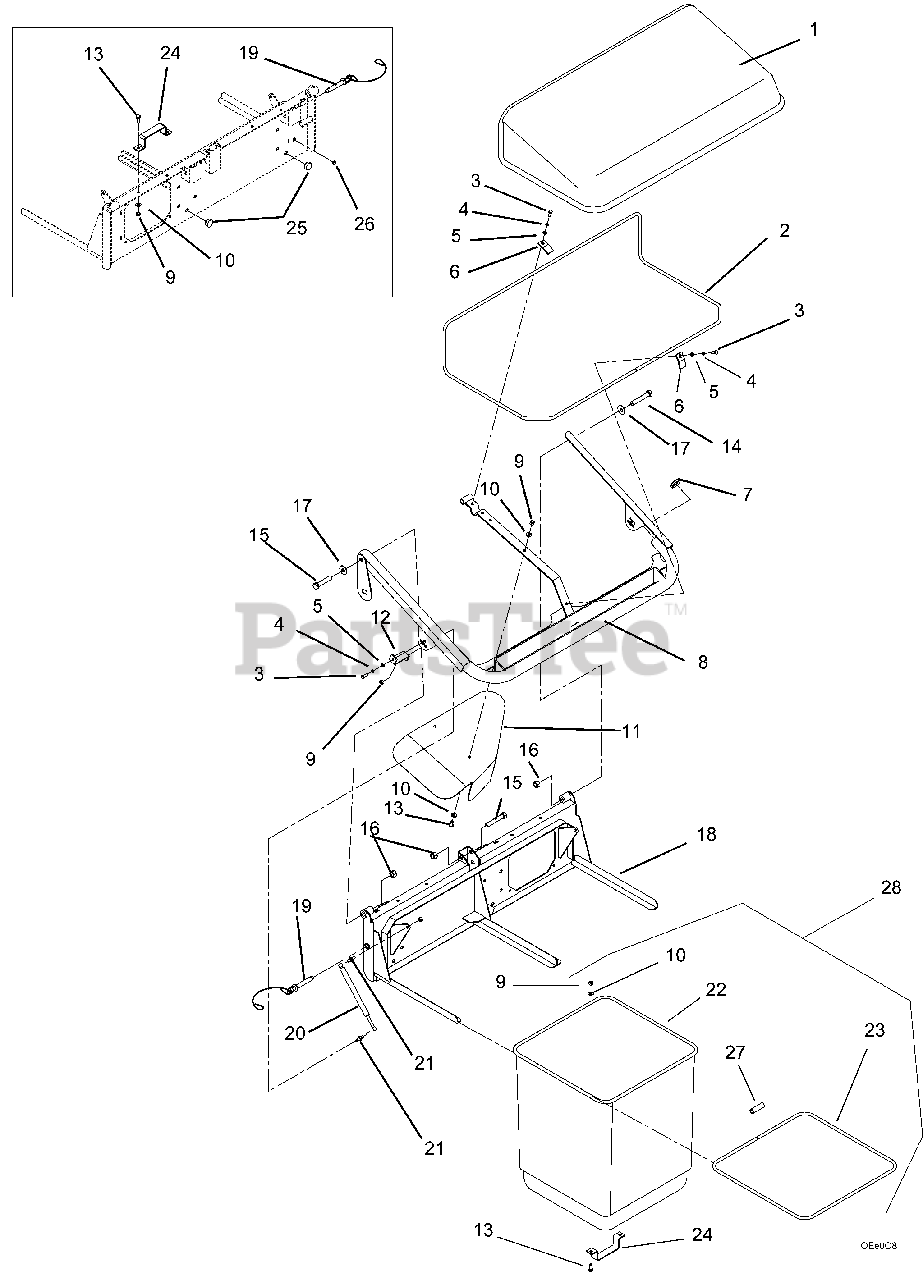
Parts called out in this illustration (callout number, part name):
1	Humboldt 2-Bag Receptacle
2	Air Dome Frame .38 Rod
3	Bolt, Hex .25-20 x .75 Grade 5
4	Washer, Locking .25 x .062
5	Washer, Flat Steel .281 x .62 x .065
6	Bracket, Mount Single Hole
7	Hole Plug, Round
8	Cap Support
9	Nut, .31-18 Nyloc Flange
10	Washer, Flat, Steel .344 x .688 x .065
11	2-Bag Deflector
12	Bracket, Gas Cylinder Mount
13	Bolt, Hex .31-18 x .75 Grade 5
14	Bolt, Hex .50-13 x 2.50 Grade 5
15	Bolt, Hex .50-13 x 3.00 Grade 5
16	Nut, Locking-Nylon .50-13
17	Washer, Flat-Steel .531 x 1.06 x .095 YWZC
18	2-Bag Support Mount
19	Detent Pin W/Lanyard 1/2 x 2-.50
20	Gas Cylinder
21	Ball Stud
22	Cloth Bag
23	Grass Bag Frame
24	Bag Handle
25	Rubber Bumper
26	Hole Plug 7/16
27	Tube Connector
28	Bag Assembly
